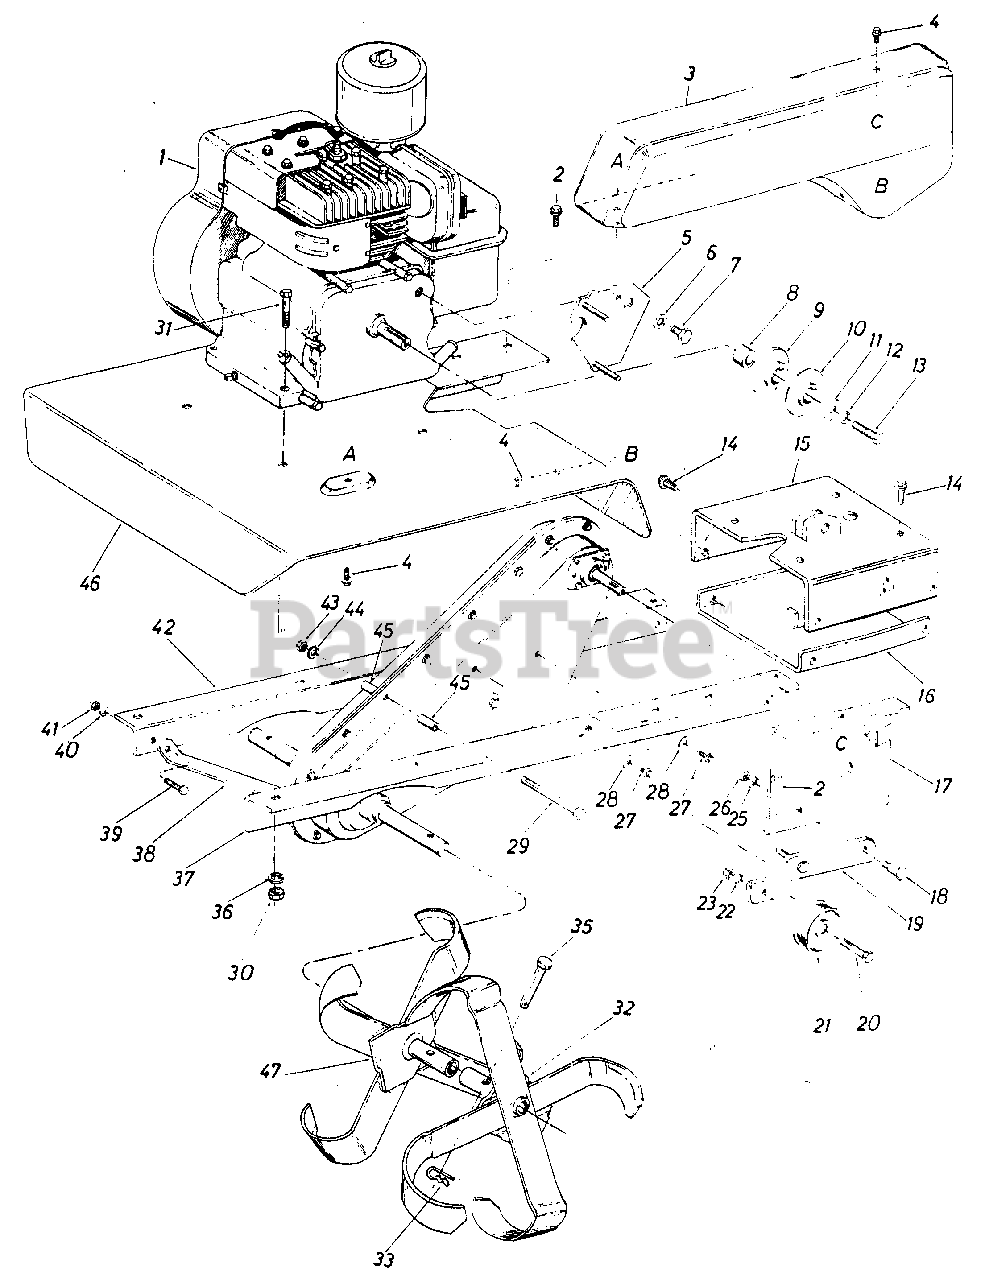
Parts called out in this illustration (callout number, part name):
1	Engine
2	Hex Wash. Hd. Self-Tap Scr. 5/16-24 x .50" Lg.
3	Belt Cover
4	Hex Wash. Hd. Self-Tap Scr. 1/4-20 x .50" Lg.
5	Belt Keeper Brk't. Ass'y.
6	Internal L-Wash. 1/2" I.D.
7	Hex Scr. 1/2-20 Thd.
8	Spacer
9	Pulley Half
10	Pulley Half
11	Fl-Wash. 3/8 I.D. x 1.25" O.D. x .100
12	L-Wash. 3/8 I.D.'
13	Hex Scr. 3/8-24 x 1.00" Lg.
14	Hex Wash. Hd. Self-Tap Scr. 3/8-24 x 7/8" Lg.
15	Handle Mounting Brk't. Ass'y.
16	U-Channel Brk't. Ass'y.
17	Idler Mounting Brk't.
18	Shld. Bolt
19	Idler Brk't. Ass'y.
20	Hex Scr. 3/8-16 x 1.50" Lg.
21	Idler Pulley
22	L-Wash. 3/8 I.D.
23	Hex Nut 3/8-16 Thd.
25	L-Wash. 3/8 I.D.
26	Hex Nut 3/8-16 Thd.
27	Hex Wash. Hd. Self-Tap Scr. 1/4-20 x .50" Lg.
28	Belleville Wash. .26 I.D. x .75 O.D. x .060
29	Hex Scr. 5/16-18 x 2.75" Lg.
30	Hex Nut 5/16-18 Thd.
31	Hex Bolt 5/16-18 x 1.50" Lg.
32	See Tine Chart
33	Hairpin Cotter
35	Clevis Pin
36	L-Wash. 5/16" I.D.*
37	Frame Rail L.H.
38	Front Brace Brk't.
39	1 Hex Scr. 5/16-18 x .75" Lg.
40	1 L-Wash. 5/16" I.D.
41	Hex Cent. L-Nut 5/16-18 Thd.
42	Frame Rail R.H.
43	Hex Cent. L-Nut 5/16-18 Thd.
44	L-Wash. 5/16" I.D.
45	Spacer
46	Tine Shield
47	See Tine Chart
